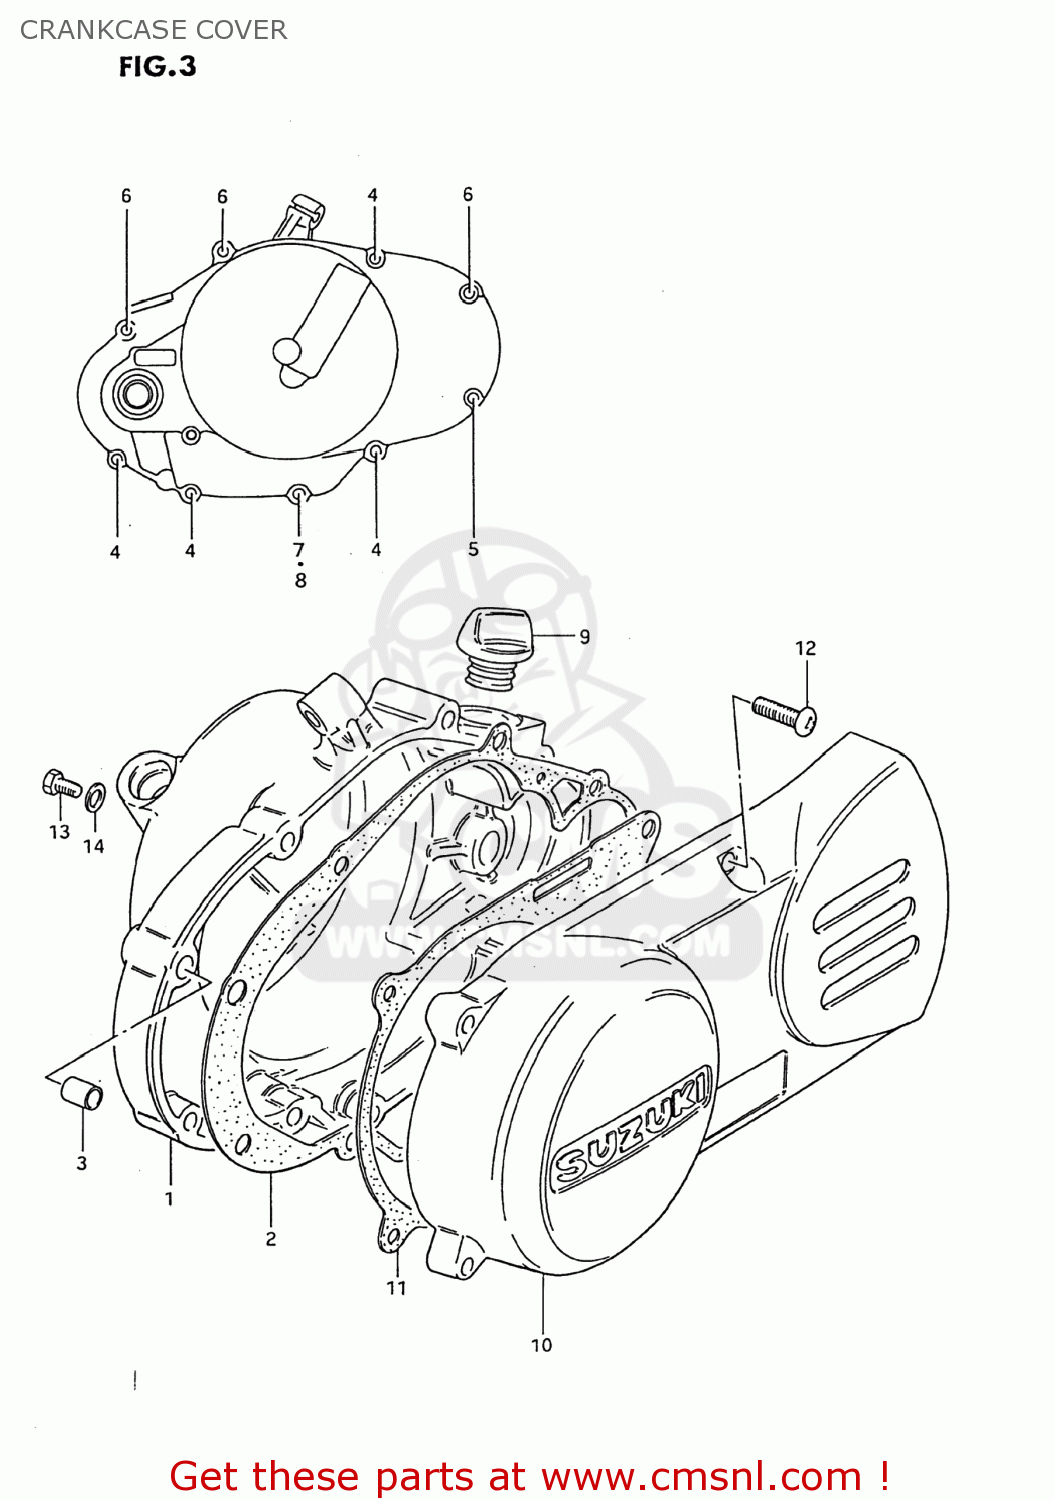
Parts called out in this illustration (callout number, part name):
1	COVER,CLUTCH
2	GASKET,CLUTCH COVER (NAS)
3	PIN
4	SCREW
5	SCREW
6	SCREW
7	SCREW
8	GASKET(6.2X11X1).2 (NAS)
9	PLUG
10	COVER,MAGNETO
11	GASKET,MAGNETO COVER (NAS)
12	SCREW
13	SCREW(6X10)
14	GASKET(6.2X11X1) (NAS)
